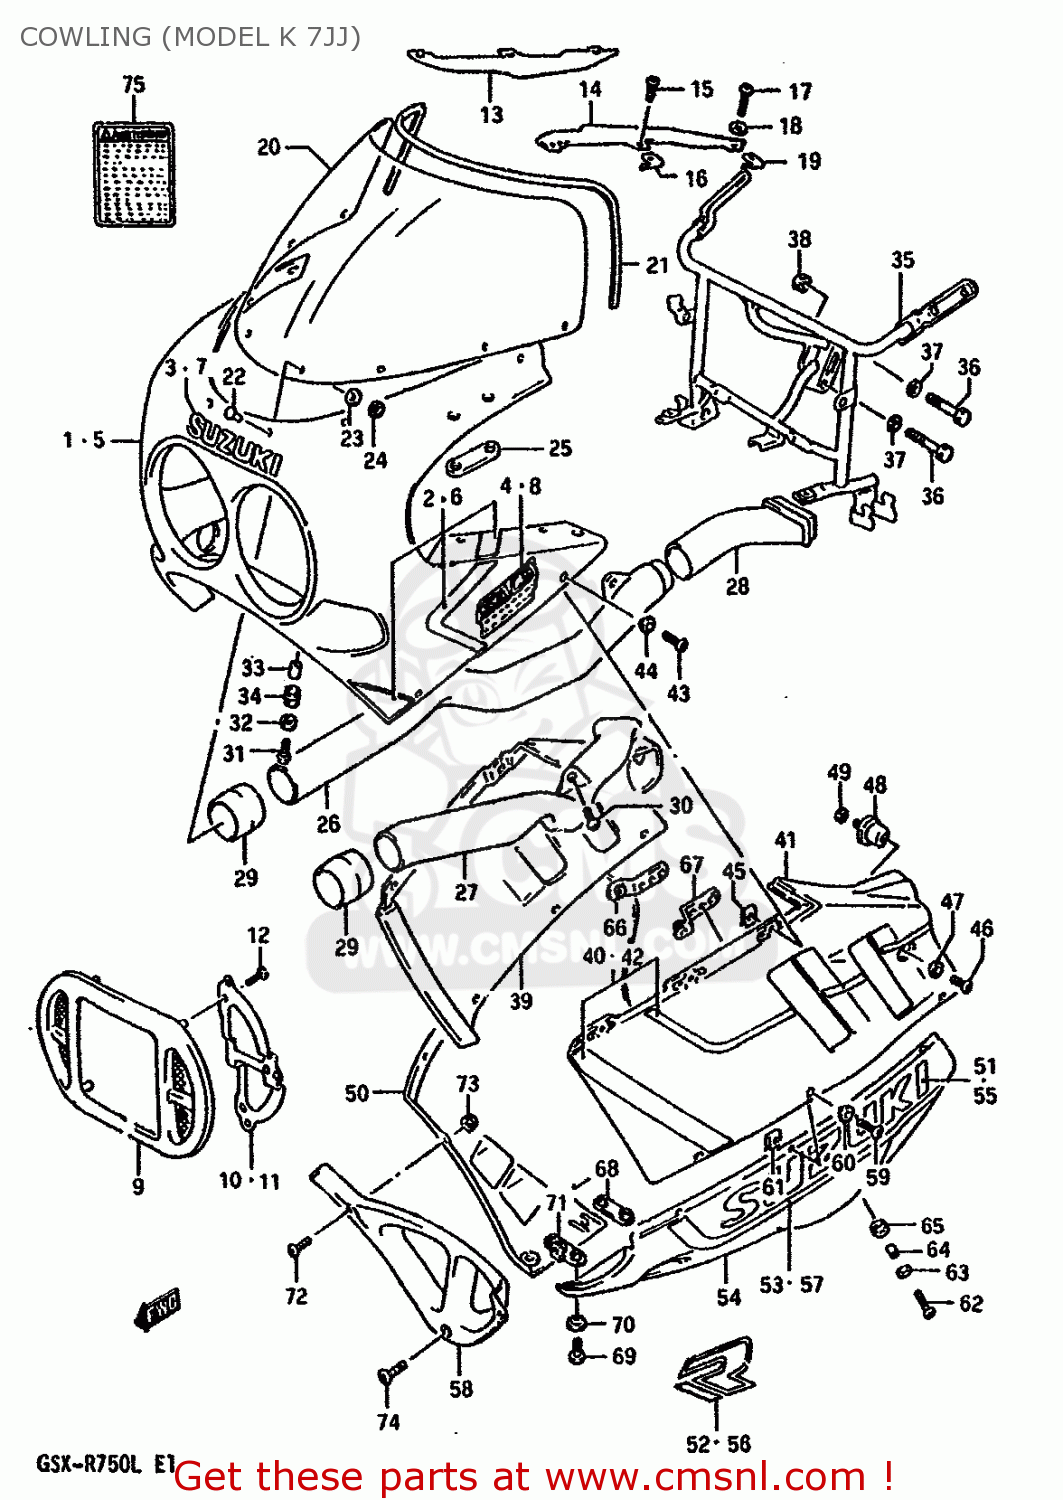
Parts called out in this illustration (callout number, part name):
1	BODY ASSY,COWLING (WHITE/RED)
2	TAPE SET,COWLING,UPPER
3	EMBLEM,COWLING,UPPER (W)
4	EMBLEM
5	BODY ASSY,COWLING (WHITE/RED)
6	TAPE SET,COWLING,UPPER
7	EMBLEM,COWLING,UPPER (W)
8	EMBLEM
9	COVER,FRONT (RED)
10	PLATE,COVER RH
11	PLATE,COVER LH
12	TAPPING SCREW 4X10/A
13	PANEL,COWLING UPPER,RIGHT
14	COVER,COWLING,LEFT
15	SCREW(5X10)
16	NUT
17	SCREW(5X14)
18	WASHER(5.2X11X1)
19	NUT
20	WINDSCREEN
21	MOLDING
22	PIN,WINDSCREEN
23	CUSHION
24	NUT
25	CUSHION,RR VIEW MIRRORR
26	PIPE,AIR INTAKE,FRONT
27	PIPE,AIR INTAKE,FRONT
28	PIPE,AIR INTAKE RR,R
29	JOINT,AIR INTAKE
30	SCREW
31	SCREW(6X20)
32	WASHER(6.5X18X1)
33	SPACER
34	CUSHION
35	BRACE,COWLING
36	BOLT
37	WASHER,LOCK,8.
38	NUT ,8MM
39	COVER,COWLING SIDE,RIGHT
40	TAPE SET,COWLING SIDE
41	COVER,COWLING SIDE,LEFT
42	TAPE SET,COWLING SIDE
43	SCREW(5X18)
44	WASHER(5.2X14X1.5)
45	NUT,HEADLAMP HOUSING,UPPER
46	SCREW(6X12)
47	WASHER(6.3X16X1.5)
48	CUSHION,COWLING
49	WASHER,LOCK
50	COWLING,UNDER,RIGHT
51	EMBLEM,COWLING SIDE (RED)
52	EMBLEM,COWLING,UNDER
53	TAPE,COWLING,UNDER,RIGHT
54	COWLING,UNDER,LEFT
55	EMBLEM,COWLING,UNDER (R)
56	EMBLEM,COWLING,UNDER
57	TAPE,COWLING,UNDER,LEFT
58	COWLING,UNDER,CENTER
59	SCREW(5X18)
60	WASHER(5.2X14X1.5)
61	NUT,HEADLAMP HOUSING,UPPER
62	SCREW(6X20)
63	WASHER(6.5X18X1)
64	SPACER
65	CUSHION
66	BRACKET
67	BRACE,COWLING UNDER,LH
68	BRACE,COWLING LWR COVER RR
69	SCREW(6X16)
70	WASHER(6.3X16X1.5)
71	BRACE,COWLING LWR COVER
72	SCREW(5X14)
73	NUT
74	SCREW(6X16)
75	LABEL (WARNING SCREEN)
